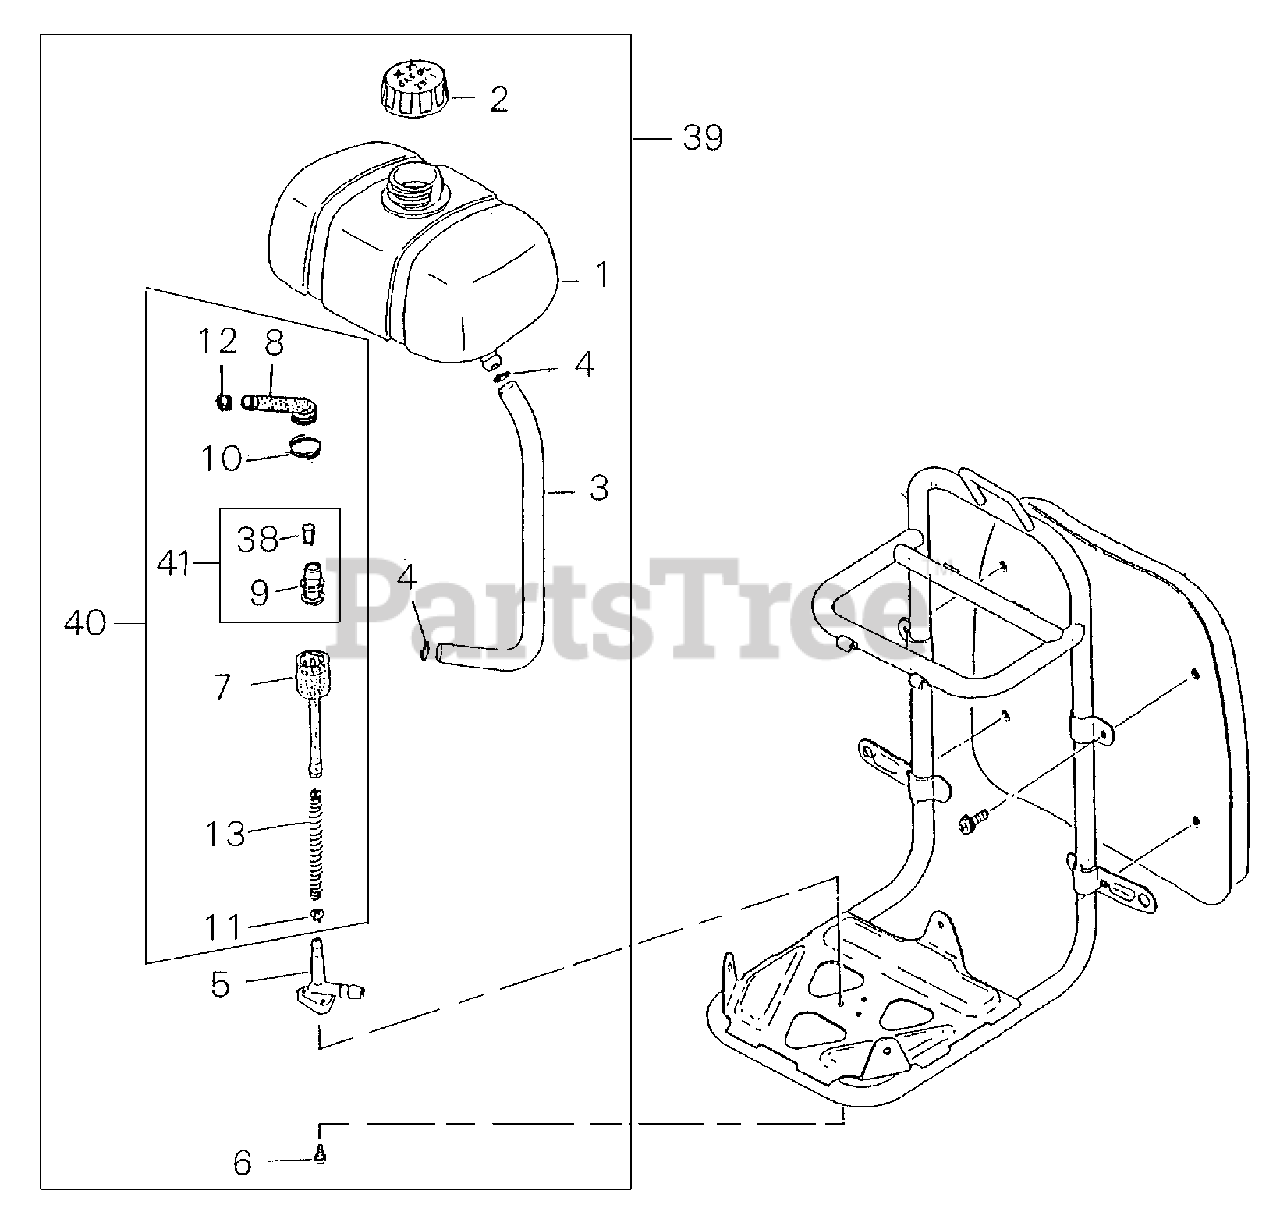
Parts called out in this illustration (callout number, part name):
1	TANK, FUEL
2	CAP ASSY
3	PIPE - FUEL
4	CLIP
5	ELBOW
6	SCREW
7	PIPE - FUEL
8	PIPE - FUEL
9	FILTER, FUEL
10	CLIP
11	CLAMP
12	CLIP
13	SPRING
38	FILTER, FUEL
39	FUEL TANK ASSY
40	FILTER, FUEL
41	FUEL FILTER ASSY
